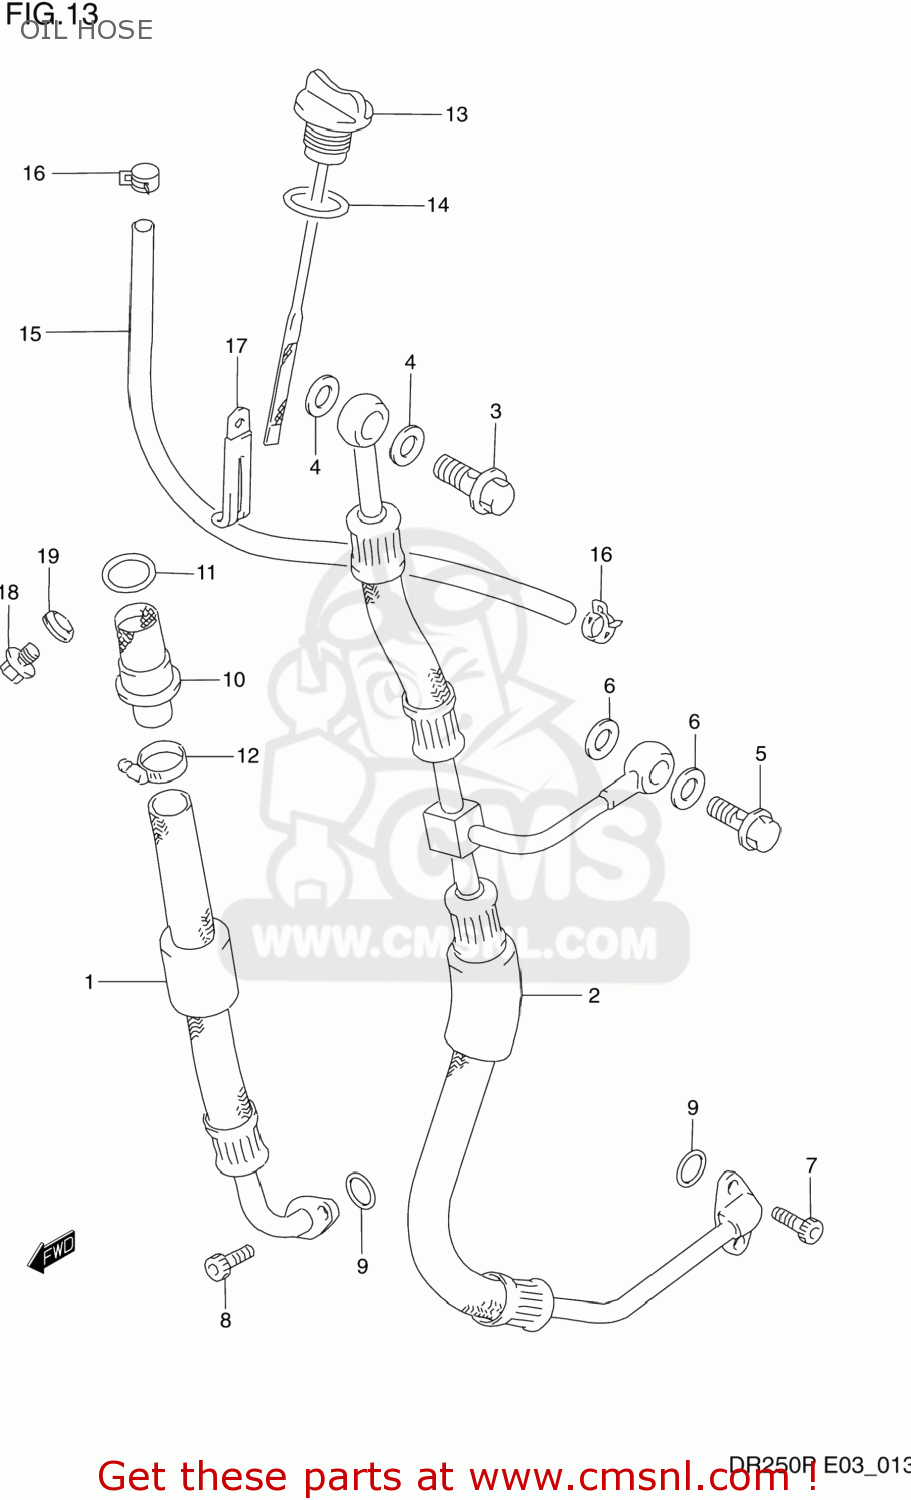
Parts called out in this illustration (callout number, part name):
1	HOSE,OIL
2	HOSE,OIL
3	BOLT UNION
4	GASKET(16X22X2) (NAS)
5	BOLT UNION
6	GASKET(12X16.5X1.5) (NAS)
7	BOLT
8	BOLT
9	O RING(D:2.4,ID:12.3)
10	STRAINER,FRAME HEAD UNDER
11	O RING(D:3.1,ID:22.7)
12	CLAMP
13	GAUGE ASSY,OIL LEVEL
14	O RING(D:3.1,ID:16.8)
15	HOSE,OIL COOLER,UPPER
16	CLAMP
17	CLAMP
18	PLUG
19	GASKET(10X14X3.6) (NAS)
